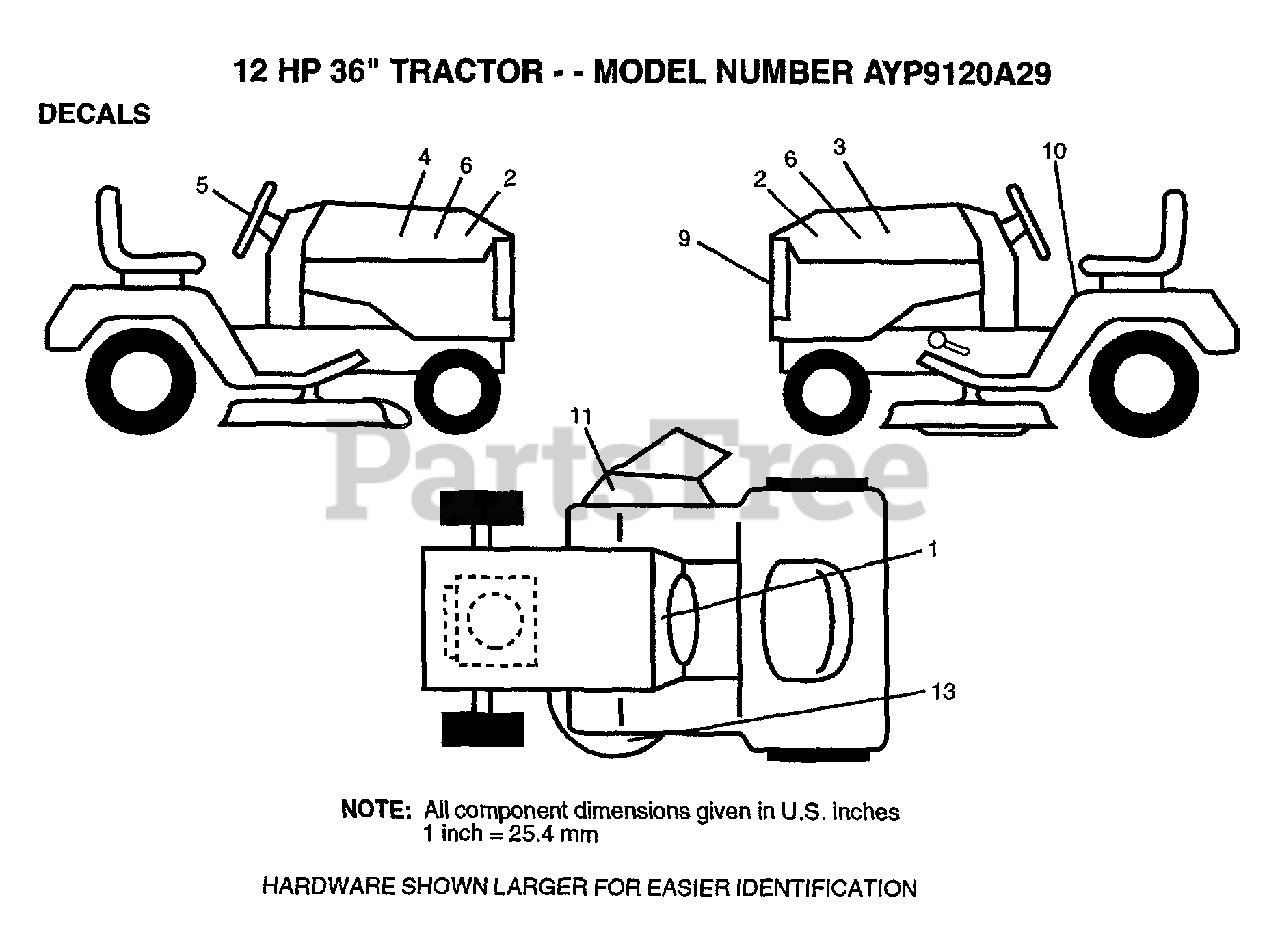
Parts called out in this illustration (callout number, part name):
3	DECAL, STRIPE, HOOD, L.H.
4	DECAL, STRIPE, HOOD, R.H.
6	DECAL, SIDE PANEL
10	DECAL
11	DECAL WARING
13	DECAL INSTRUCTION CAUTION
